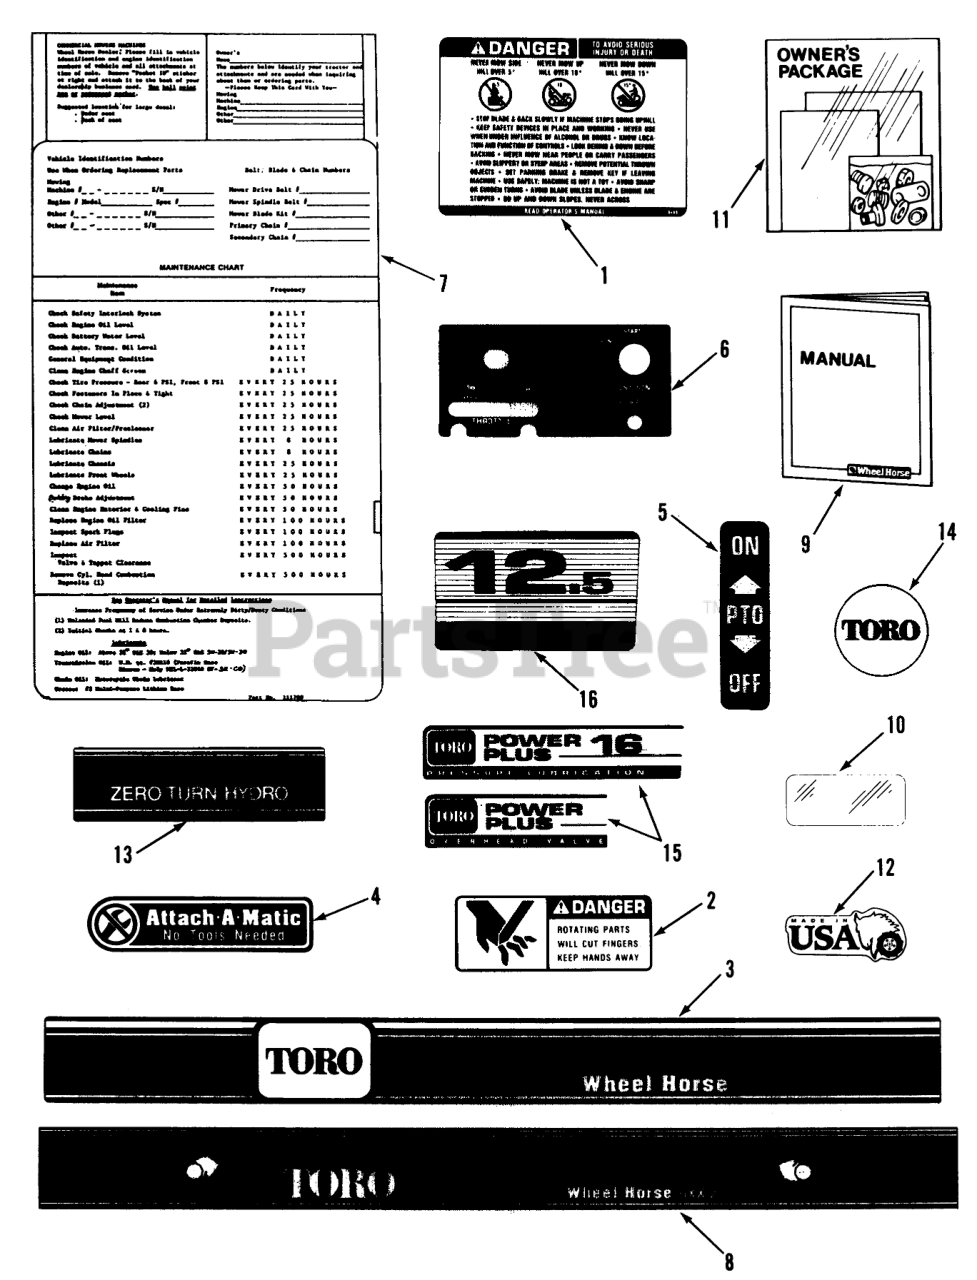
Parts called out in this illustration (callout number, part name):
1	DECAL-DANGER
2	DECAL-DANGER
3	DECAL-REAR 600
4	Decal-Attac-O-Matic
5	DECAL-PTO
6	DECAL-CONTROL
7	MAINTENANCE-DECAL
8	DECAL-FRONT 612-Z
9	Operator-s Manual
10	Vin Tag Overlay 616-Z
11	Loose Parts Package
12	Decal-Made In USA
13	DECAL-ZERO TURN HYD
14	NAME-PLATE TORO LOGO
15	DECAL POWER PLUS 16
16	DECAL-PWR PLUS 12.5
